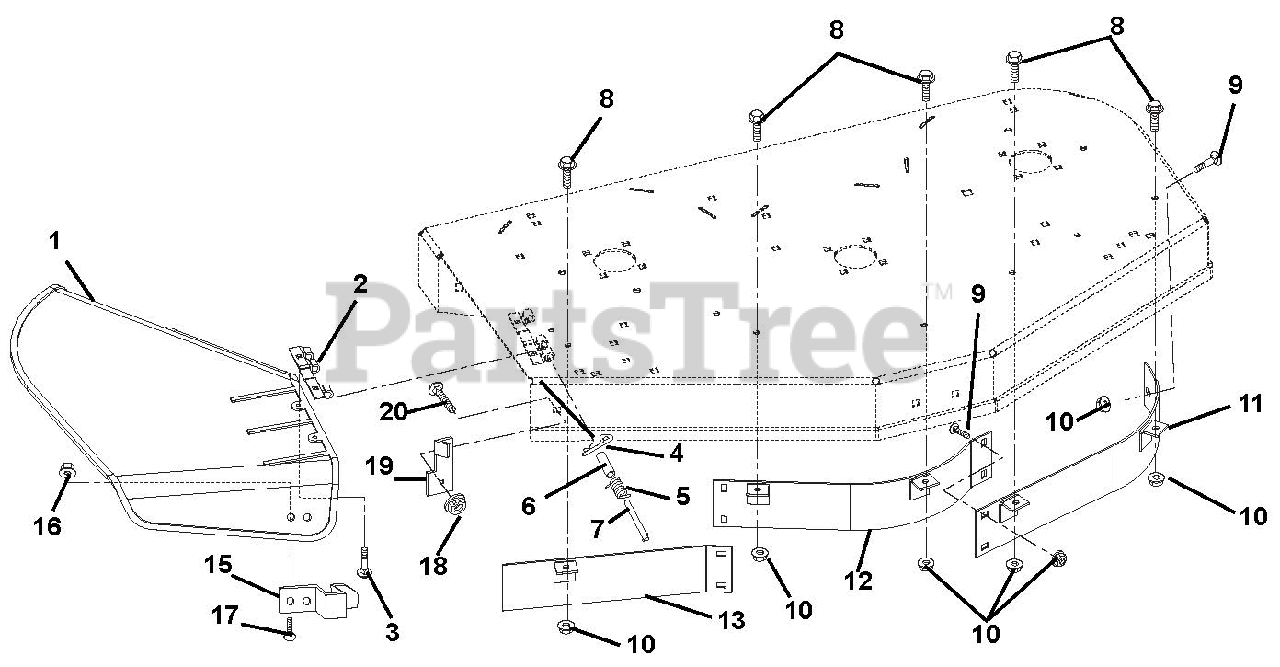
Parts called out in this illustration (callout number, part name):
1	Deflector, Chute
2	Hinge, Plate
3	Bolt, Round Head Square Neck .25-20 x .75 Grade 5
4	Pin, Hair Internal .08 x .18 x 1.18
5	Spring, Torsion .095 x .50 x 1.00
6	Bushing, Sleeve
7	Clevis Pin
8	Bolt, Serrated Hex Flange Washer Head .312-18 x .75
9	Bolt, Round Head Square Neck .31-18 x .62
10	Nut-5/16-18 Flange Nyloc
11	Weldment, Upper Left Baffle-40"
12	Weldment, Upper Center Baffle-40"
13	Weldment, Upper Right Baffle-40"
15	Flat Spring
16	Nut, Locking Top Flange .25-20
17	Bolt, Round Head Square Neck .25-20 x .50 Grade 5
18	Nut-3/8-16 Flange Nylon
19	Bracket, Chute Lock
20	Bolt, Round Head Square Neck .38-16 x 1.50
